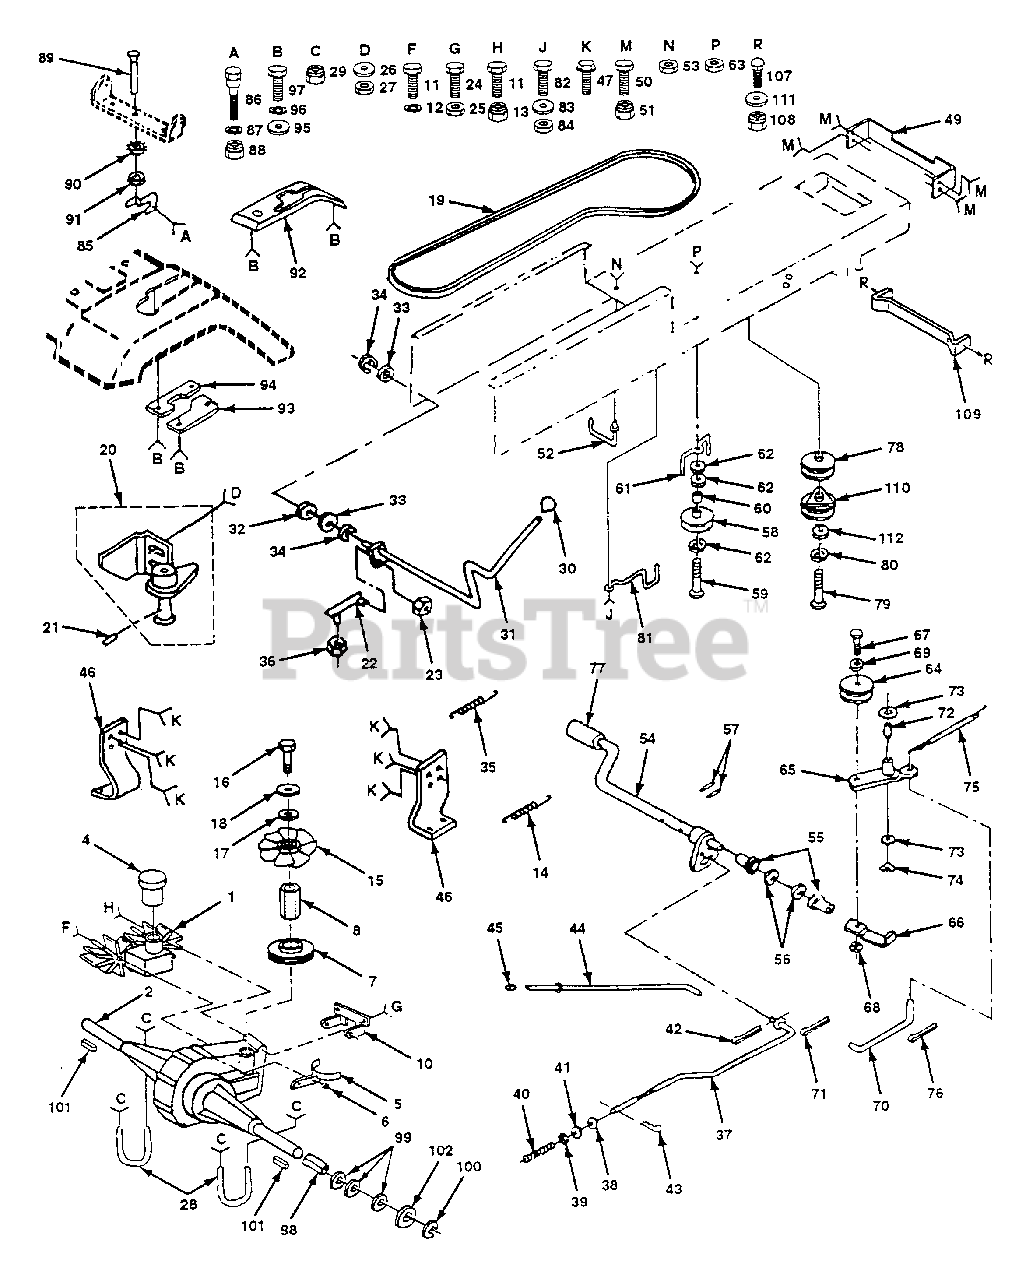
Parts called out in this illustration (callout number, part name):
1	Sunstrand Pump, Hydro
2	Transaxle Assembly.
4	Resevoir, Transaxle Pump
5	Belt Keeper, Transaxle
6	Nut, Crownlock 1/4-20 Unc
7	Transaxle Pulley
8	Spacer, Stand-off, Transaxle Fan
10	Bracket, Differential Mounting
11	Bolt, Hex 5/16-18uncx4 5 Gr. 5
12	Washer, Lock 5/16
13	Nut, Crownlock 5/16-18
14	Spring Return Brake
15	Fan, Transaxle Hydro 7"
16	Bolt, Hex 1/4-20unc X 75
17	Washer 9/32 X 1-1/4 X 16 Ga
18	Washer, Lock, Hlcl 1/4
19	V-Belt, Ground Drive
20	Friction Pack Assembly
21	Pin, Roll 198 X 866
22	Rod, Tie Hydro Stretch
23	Nut, Hex, Flange 1/4-28 Unf
24	Bolt, Hex 3/8-16unc X 3/4
25	Nut, Crownlock 3/8-16 Unc
26	Washer 13/32 X 3/4 X 16 Ja
27	Nut. Crownlock 3/8-16 Unc
28	U-Bolt 3/8-16 X 2 83
29	Nut, Crownlock 3/8-16 Unc
30	Knob 1/2-13
31	Control Lever Assembly
32	Bushing, Transaxle
33	Washer, Shim .53 X 1 25 X .0598
35	Spring Extension
36	Nut, Hex, Flange 1/4-28 Unf
37	Rod, Brake
38	Locknut 3/8-16unc
39	Nut, Hex Jam 3/8-16 Unc
40	Spring, Brake Rod
41	Washer 13/32 X 13/16 X 16 Ga
42	Retainer Spring
43	Retainer Spring
44	Rod, Parking Brake
45	Cap, Parking Brake
46	Bracket, Transaxle
47	Screw, Thd., Roll. 3/8-16 X 1 Ty-tt
49	Bracket, Mounting
50	Bolt, Carriage 3/8-16 x 3/4
51	Nut, Crownlock 3/8-16 Unc
52	Keeper, Center Span
53	Nut, Crownlock 3/8-16 Unc
54	Shaft, Foot Pedal
55	Bearing, Nylon
56	Washer 21/32 X 1 X 16 Ga
57	Pin Roll 3/16 X 1
58	Pulley, Idler, Flat
59	Bolt, Hex 3/8-16unc X 2-3/4
60	Spacer, Split
61	Keeper, Belt Retainer
62	Washer 13/32 X 13/16 X 12 Ga
63	Nut, Crownlock 3/8-16 Unc
64	Pulley, Idler, V-Groove
65	Bellcrank Assembly
66	Retainer Belt
67	Bolt, Hex 3/8-16unc X 1-1/2
68	Nut, Crownlock 3/8-16 Unc
69	Washer 13/32 X 13/16 X 16 Ga
70	Link, Clutch
71	Cotter Pin 1/8 X 3/4
72	Nylon Bearing
73	Washer, Hardened
74	Ring, Klip #t5304-50
75	Spring, Return, Clutch
76	Cotter Pin 1/8 X 3/4
77	Cover Pedal
78	Pulley, Engine
79	Bolt, Hex M10-1.5 x 110
80	Washer, Lock, Hlcl 7/16
81	Keeper, Belt, Engine, LH
82	Bolt, Hex 3/8-16unc X 1
83	Washer 13/32 X 13/16 X 12 Ga
84	Nut, Crownlock 3/8-16 Un
85	Arm, Control
86	Bolt, Shoulder 1/4 X 20 Unc
87	Washer, Spring, Oiled
88	Nut, Crownlock 1/4-20 Unc
89	Control, Bypass
90	Washer, Lock, Ext. Teeth 3/8
91	Nut, Hex, Fin. 3/8-24 Unf
92	Console. Shift
93	Plate, Neutral Adjust, RH
94	Plate, Neutral Adjust, LH
95	Washer 9/32 X 3/4 X 16 Ga
96	Washer, Lock, Hlcl 1/4
97	Bolt, Hex 1/4-20unc X 1/2
98	Spacer, Split
99	Washer 25/32 X 1 1 /4 X 16 Ga
100	E-Ring #5133-75
101	Key, Square
102	Washer 25/32 X 1-5/8 X 16 Ga.
107	Bolt Carriage 5/16-18 x 3/4
108	Nut, Crownlock 5/16-18
109	Bracket, Asm. Clutch
110	Clutch Electric
111	Washer 11/32 x 5/8 x 12 Ga.
112	Washer 1-1/2 OD x 15/32 ID x .250
